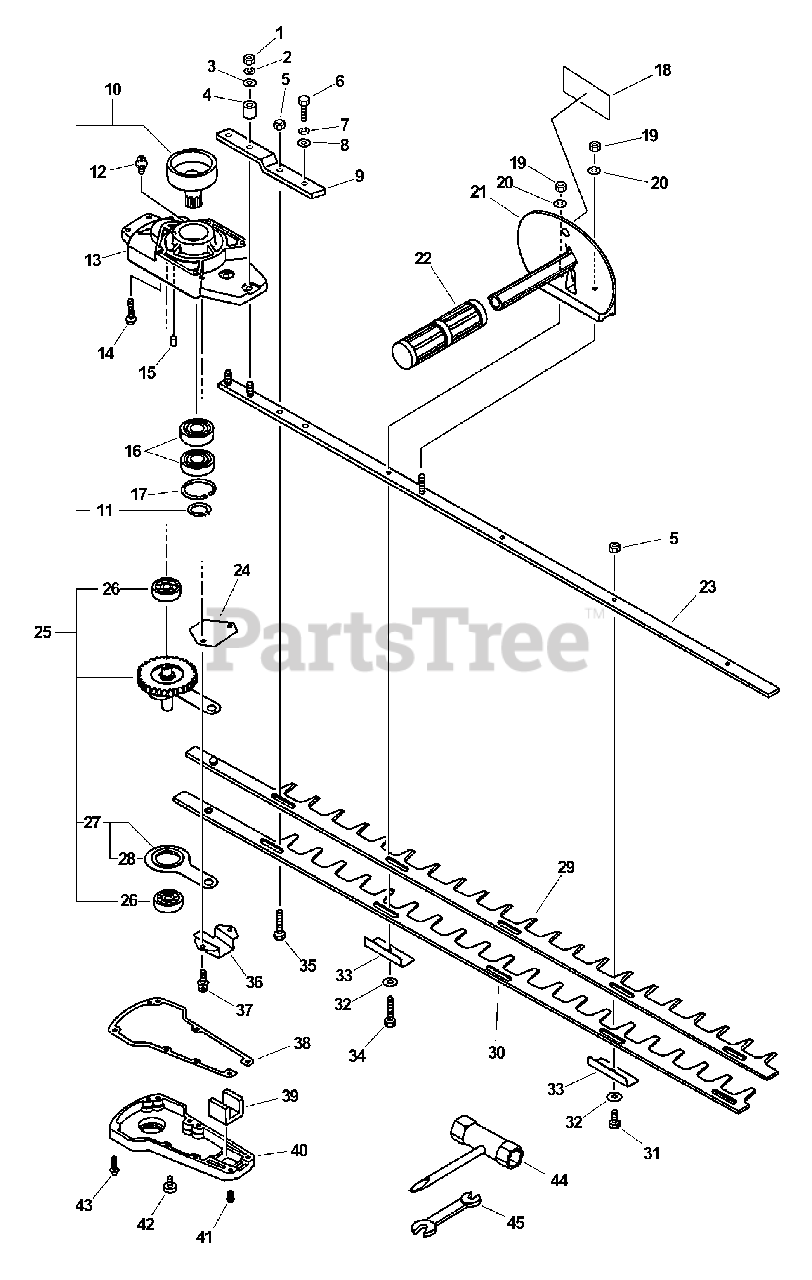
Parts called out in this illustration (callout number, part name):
1	LOCKNUT - 6
2	LOCKWASHER - 6
3	WASHER - 6
4	SPACER
5	LOCKNUT - 6
6	BOLT - 6X10
7	LOCKWASHER - 6
8	WASHER - 6
9	BRACKET, ANGLE
10	DRUM, CLUTCH
11	RING, RETAINING - 16
12	FITTING, GREASE
13	CASE, GEAR
14	SCREW - 5X30
15	PIN - LOCATING
16	BEARING, BALL - 6003
17	RING, RETAINING - 35
18	LABEL - CAUTION
20	WASHER - 6
21	HANDLE ASSY - FRONT
22	GRIP, HANDLE
23	SUPPORT, BLADE
24	PLATE, GUIDE
25	GEAR ASSY
26	BEARING, BALL - 6200
27	CONNECTING ROD ASSY
28	BEARING, NEEDLE
29	BLADE - UPPER
30	BLADE - LOWER
31	BOLT
32	WASHER
33	INSULATOR
35	BOLT - 6
36	GUIDE
37	SCREW - 5X14
38	GASKET, GEAR CASE
39	SEAL, FELT
40	LID, GEAR CASE
41	SCREW - 4X14
42	BOLT - 8X8
43	SCREW - 4X22
44	T-WRENCH - 13X19mm
45	SPANNER - 8X10mm
